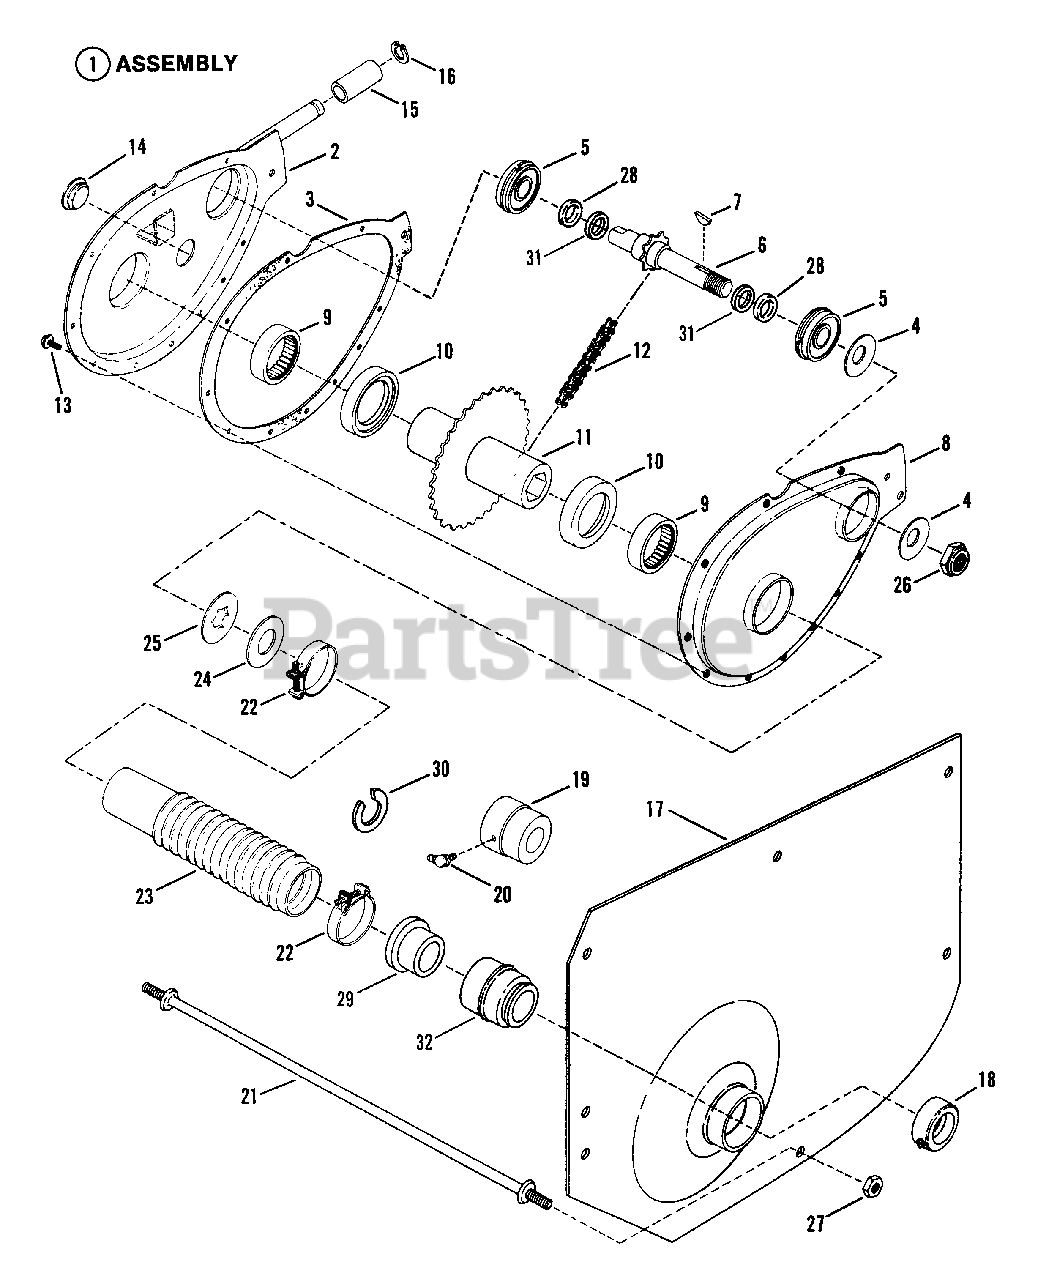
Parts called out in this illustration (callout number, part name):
1	ASSEMBLY, Chain Case
2	CASE, Sprocket
3	GASKET, Case Cover
4	WASHER, Belleville
5	BEARING, Ball
6	SPROCKET & SHAFT
7	KEY, 1/8 x 5/8" Woodruff
8	COVER, Chain Case
9	BEARING, Needle
10	WASHER, Nylon Thrust
11	HUB & SPROCKET
12	CHAIN
13	SCREW, #10-24 x 1/2" Hex Washer Self-Tap (Torx)
14	PLUG, Oil Fill & Check
15	ROLLER
16	RING, Retaining
17	FENDER, Left Hand
18	COLLAR, Lock
19	BEARING, Left Hand Fender
20	FITTING, Lube
21	ROD, Cross-Tie
22	CLAMP, Boot
23	BOOT, Oil Seal
24	WASHER, Thrust Nylon
25	WASHER, Thrust
26	NUT, 5/8-18 Hex Lock
27	NUT, 5/16-24 Hex Flange Lock
28	O-RING
29	SPACER
30	WASHER, Shim
31	WASHER, Shim
32	BEARING, Left Hand Fender
